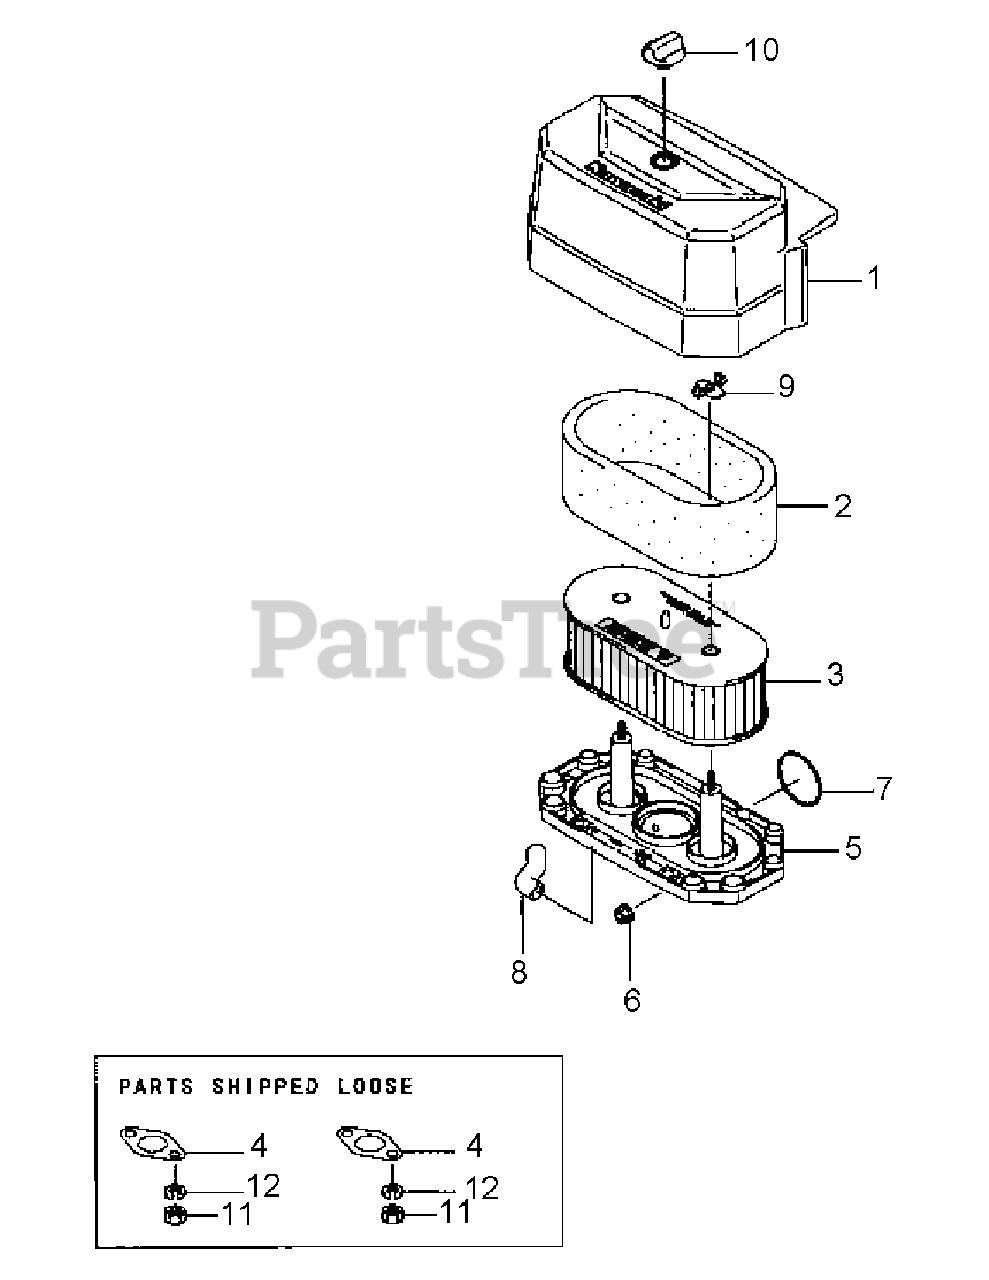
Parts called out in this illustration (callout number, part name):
1	AIR FILTER CASE
2	PRE FILTER ELEMENT
3	AIR FILTER ELEMENT
4	MUFFLER GASKET
12	SPRING WASHER
